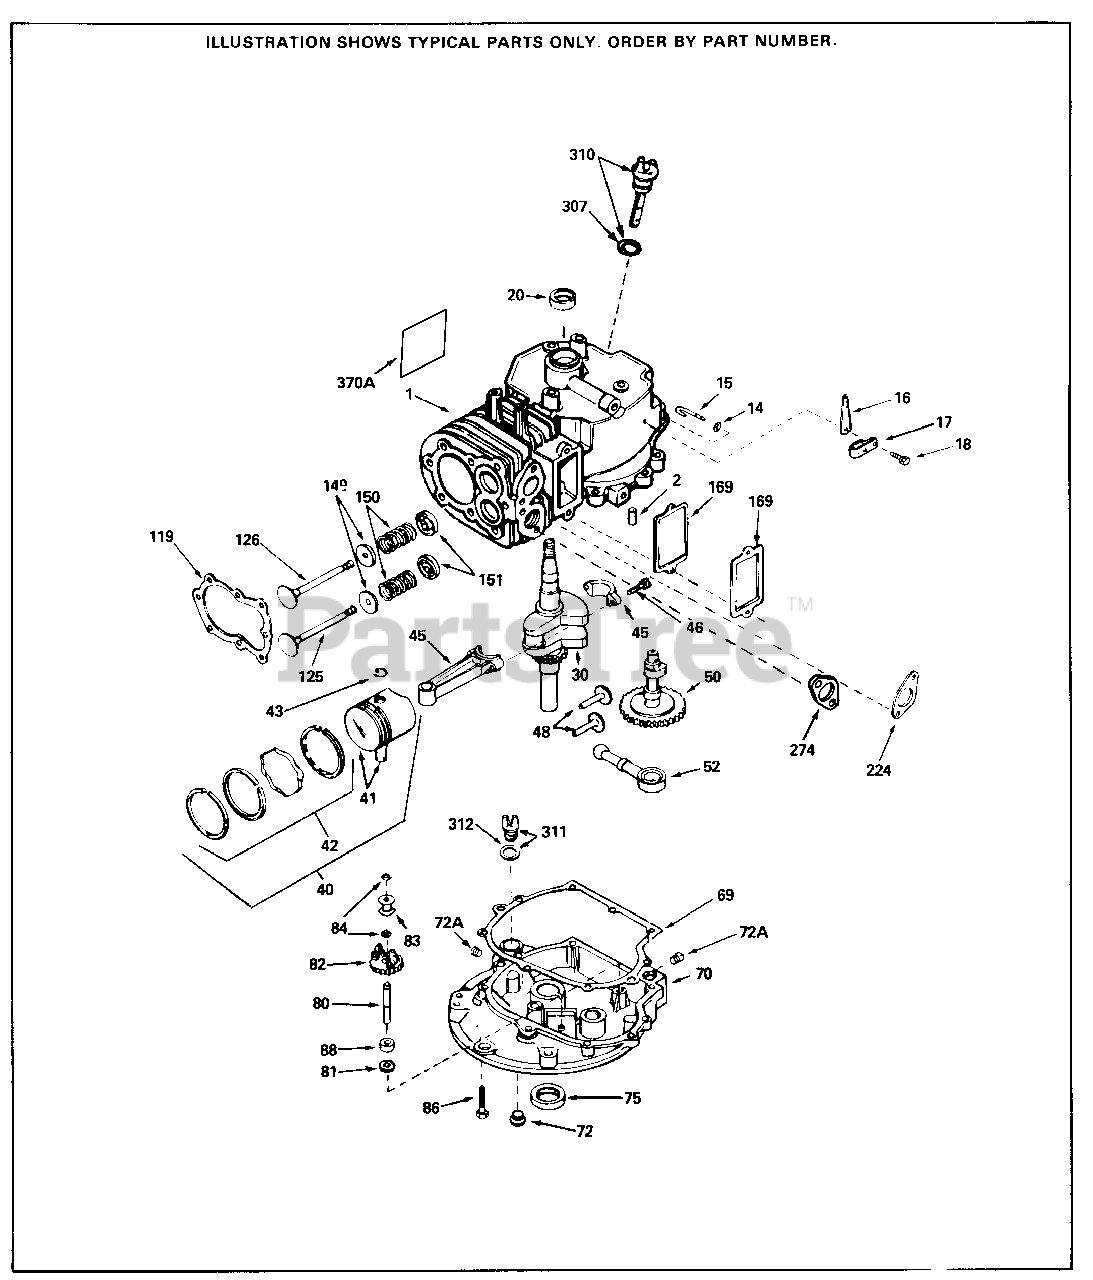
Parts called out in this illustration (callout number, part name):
1	"Cylinder (Incl. 2, 20, 311 & 312)
2	Dowel Pin
14	Flat Washer
15	Governor Rod (Incl. 14)
16	Governor Lever
17	Governor Lever Clamp
18	Screw, Torx T-15, 8-32 x 19/64"
19	Oil Seal
30	Crankshaft
40	Piston, Pin & Ring Set (.010" OS)
40	Piston, Pin & Ring Set (.020" OS)
40	Piston, Pin & Ring Set (Std.) 2-5/8"B ore
41	Piston & Pin Ass'y. (Std.)(Incl. 16) 2-5/8"
41	Piston & Pin Ass'y. (.010" OS) Incl. 43
41	Piston & Pin Ass'y. (.020" OS) Incl. 43
42	Ring Set (Std.) (2-5/8" Bore)
42	Ring Set (.010" OS)
42	Ring Set (.020" OS)
43	Piston Pin Retaining Ring
45	Connecting Rod (Incl. 46)
46	Connecting Rod Bolts (2 pcs.)
48	Valve Lifter
50	Oil Pump Assembly
50	Camshaft (MCR)
69	Mounting Flange Gasket
70	Mounting Flange Incl. 72,75,80,81,311 & 312
72	Oil Drain Plug (Sq. hd., 1/4-18)
72A	Oil Drain Plug (Sq. hd., 1/4-18)
75	Oil Seal
80	Governor Shaft
82	Governor Gear Ass'y (Incl. 81)
83	Governor Spool
84	Retaining Ring
86	Screw, 1/4-20 x 1-1/4"
88	Spacer (Incl. 81)
119	Cylinder Head Gasket
125	Exhaust Valve (Std.)(Incl. 151)
125	Exhaust Valve (1/32" OS) (Incl. 151)
126	Intake Valve (Std.) (Incl. 151)
126	Intake Valve (1/32" OS) (Incl. 151)
149	Valve Spring Cap
149	Valve Spring Cap (Lower)
150	Valve Spring
169	Valve Cover Gasket
224	Intake Pipe Gasket
274	Exhaust Gasket
310	Dipstick
311	Oil Fill Plug (Incl. 312) also availa ble in Packaged Part #740079
312	Oil Fill Plug Gasket
370	Instruction Decal
370A	Identification Decal
